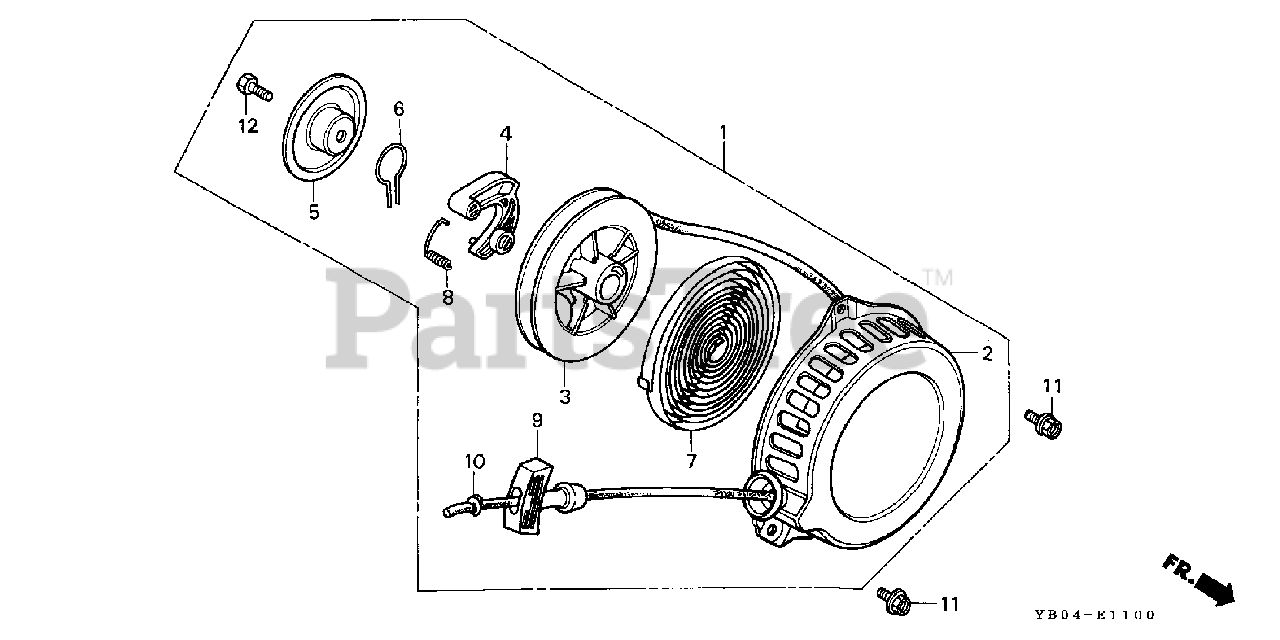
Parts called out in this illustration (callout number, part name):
1	STARTER ASSY., RECOIL
2	CASE, STARTER
3	PULLEY, RECOIL STARTER
4	RATCHET, STARTER
5	PLATE, FRICTION
6	SPRING, FRICTION
7	SPRING, RETURN
8	SPRING, RETURN
9	KNOB, STARTER (NOT AVAILABLE)
10	ROPE, RECOIL STARTER (#4X55")
10	ROPE (#4X55")
11	BOLT, FLANGE (6X8)
12	BOLT, HEX. (6X20)
